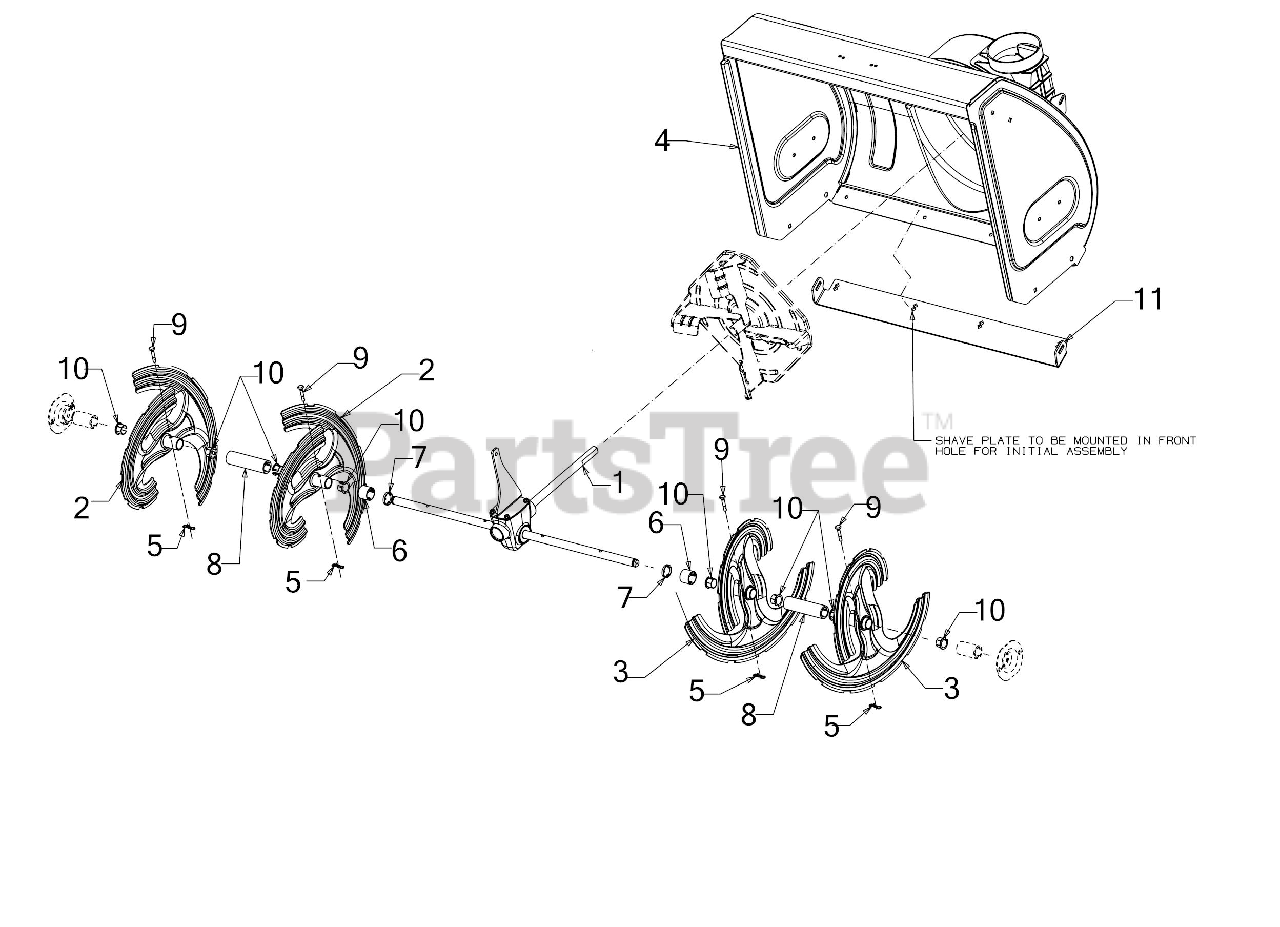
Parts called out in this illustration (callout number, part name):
1	30" AUGER GEARBOX ASSEMBLY
5	BOW TIE COTTER PIN 1/4-5/16
6	SPACER 1.25OD x .75ID X1.00 LG
7	SPCR 1.25 OD x 75IDX2.00LG
8	SPACER 1.25OD X .75ID X 4.470 LG
9	SHEAR PIN .25 x 1.50 GR2
10	FLANGE BUSHING
